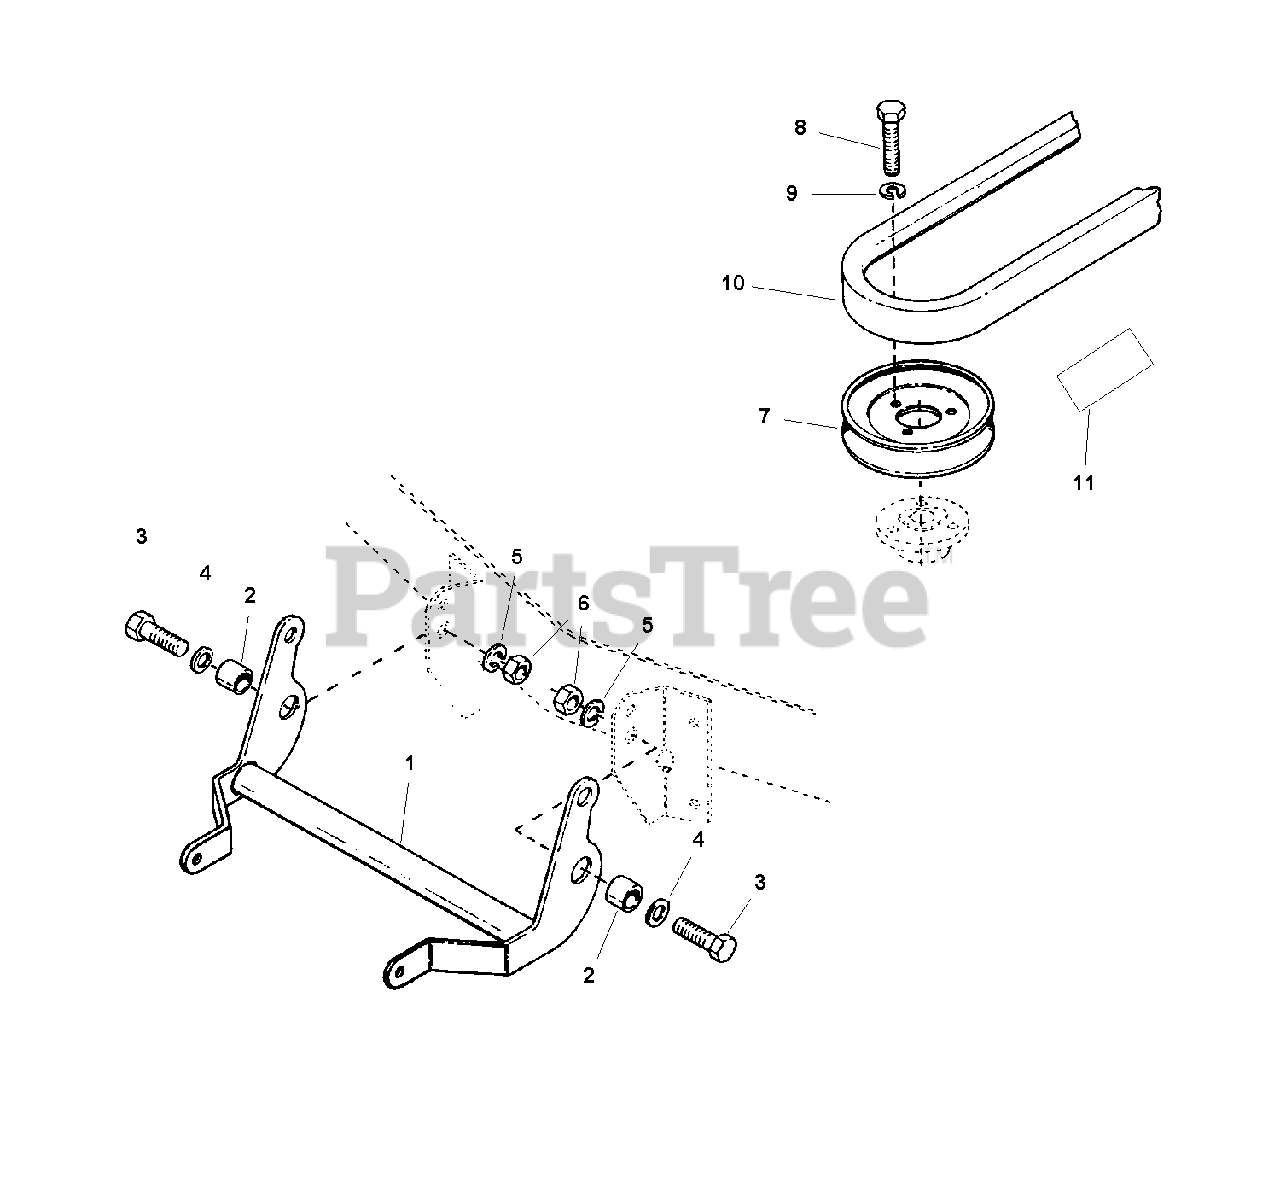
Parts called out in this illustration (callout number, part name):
1	ROCKER ARM ASSEMBLY
3	CAPSCREW, Hex Head, 1/2-13 x 1-1/4
5	LOCKWASHER
6	NUT, Hex, 1/2-13
8	CAPSCREW, Hex Head, 3/8-16 x 1-3/4
9	LOCKWASHER
11	DECAL, Installation
